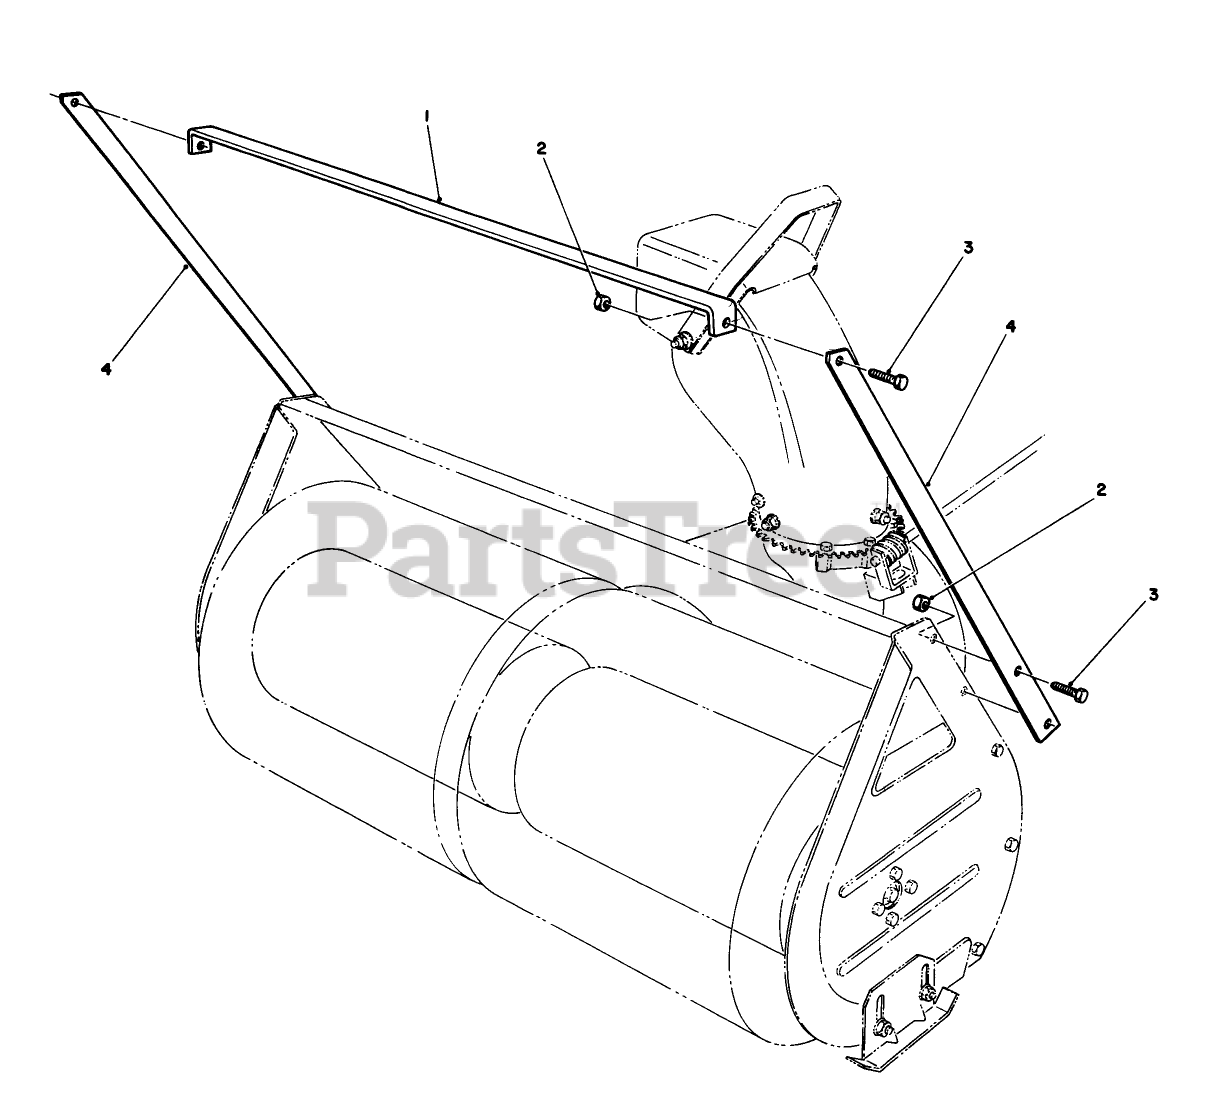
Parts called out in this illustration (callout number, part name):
1	32 TOP DRIFT BREAKER
2	NUT-LOCK, CONE
3	Screw
4	SIDE DRIFT BREAKER
